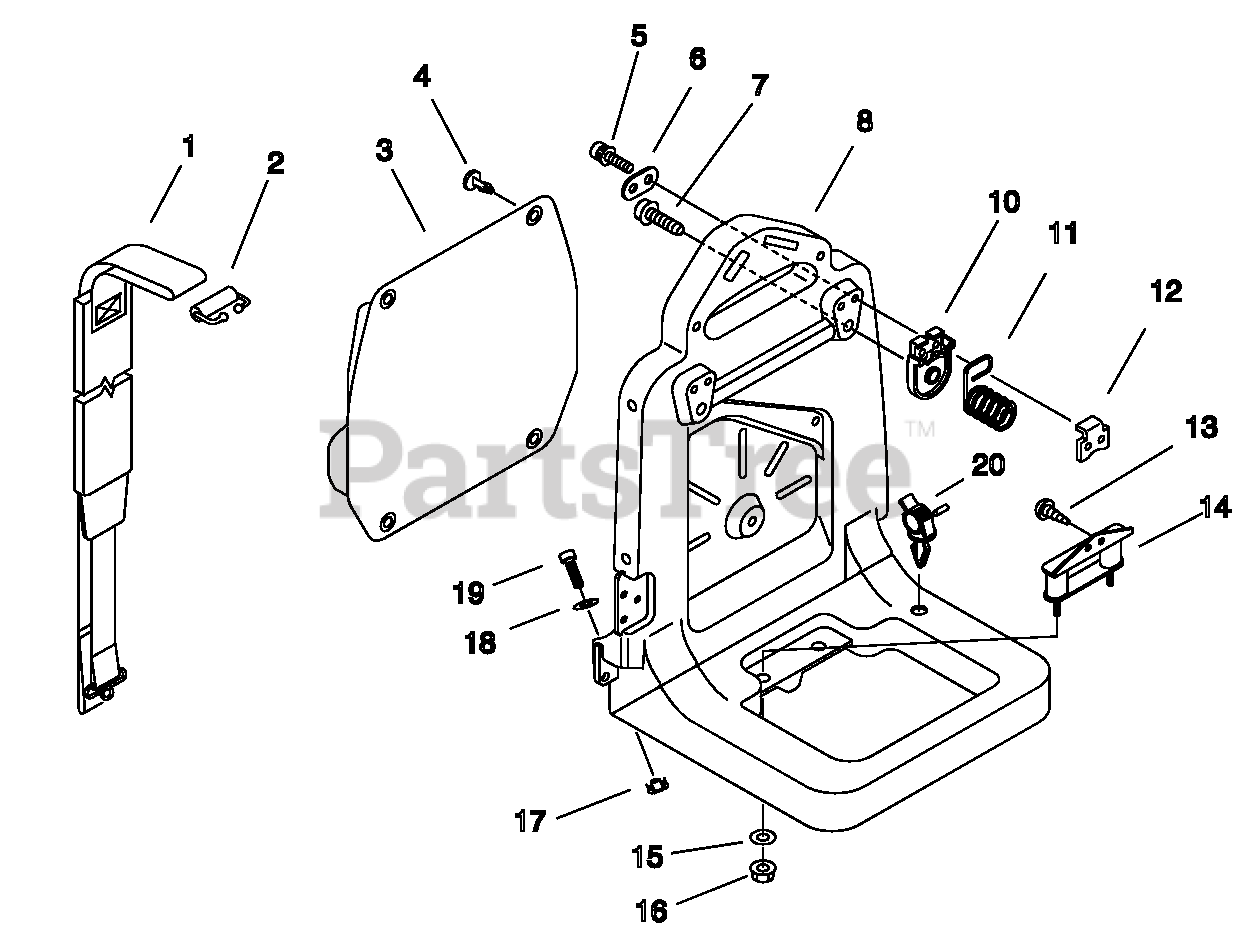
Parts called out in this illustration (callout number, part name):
1	BACKPACK STRAP ASSY
3	CUSHION, BACKPACK
5	SCREW - 5X20
7	SCREW - 5X20
8	WASHER - 5
9	FRAME, BACKPACK
10	BRACKET, SPRING
12	RETAINER
13	SCREW - 5X16
14	CUSHION
15	WASHER - 5
16	NUT - 5 -- FLANGE
18	WASHER - 6
19	SCREW - 6X25
20	CLIP, CABLE
